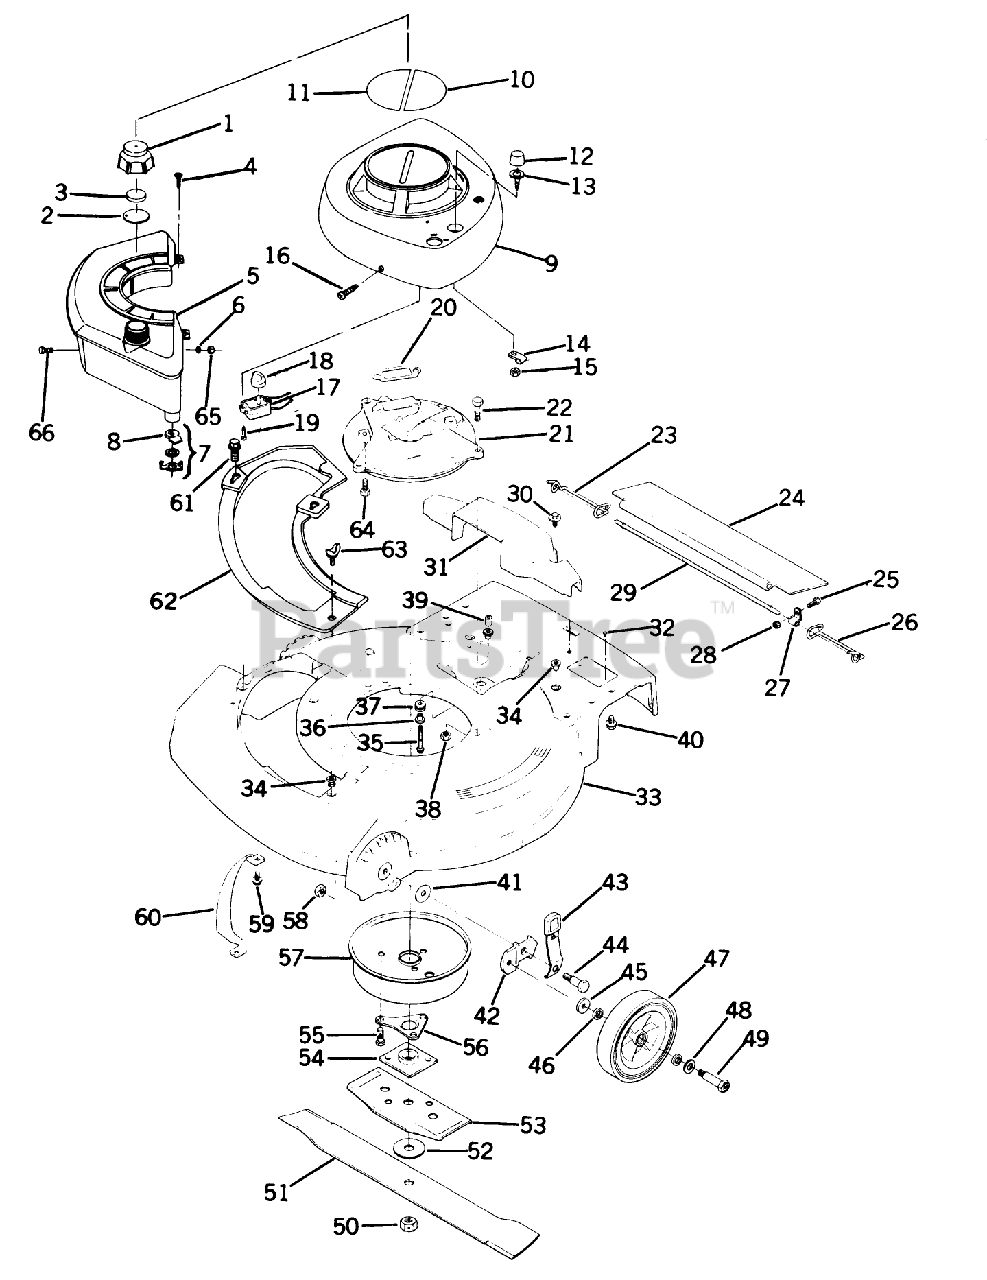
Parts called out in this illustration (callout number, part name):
2	GASKET S
3	BAFFLE - FOAM SM
4	SCREW F
7	SHUT OFF VALVE KIT
15	LOCKNUT S
16	SCREW F
18	SWITCH KNOB
22	SCREW
23	SPRING;TRAILING SHIELD RH
24	SHIELD
26	SPRIG T/SHLD ASOC
27	CLAMP ROD KMC
28	LOCKNUT E
29	ROD 21" ADVANCE
30	SCREW SEMS TRM HEX HD
36	SPACER ECK PRES
37	GROMMET
38	NUT-LOCK F
39	SPACER
40	SCREW
41	WASHER
45	WASHER WROUGHT
46	WASHER
47	WHEEL & TIRE KIT
48	SPACER
49	BOLT WHEEL
50	NUT-BLADE
52	WASHER
54	PLATE AND COLLAR ASM
55	SCREW
56	SUPPORT F
58	LOCKNUT
60	BAR-TOE
63	WING SCREW LAWRE
64	SCREW V
